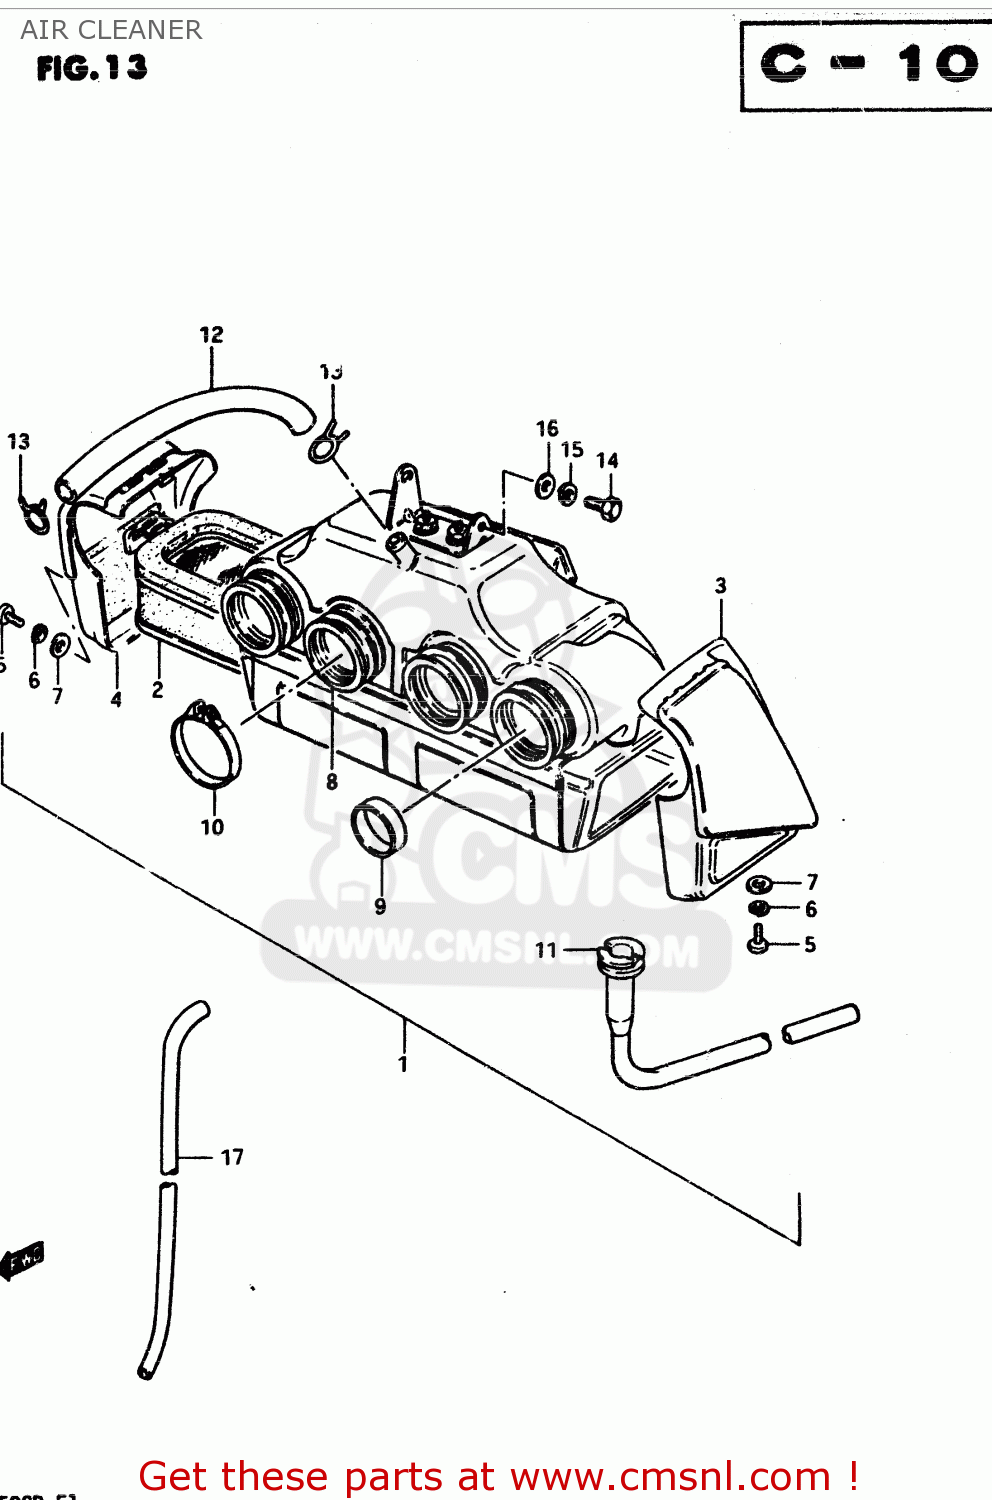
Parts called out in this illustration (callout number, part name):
1	CLEANER ASSEMBLY,AIR
2	FILTER ASSY
3	CAP,AIR CLEANER
4	CAP,AIR CLEANER
5	SCREW
6	LOCK WASHER
7	WASHER
8	TUBE,OUTLET
9	RING
10	CLAMP
11	DRAIN TUBE
12	TUBE,BREATHER
13	CLIP
14	BOLT
15	LOCK WASHER
16	WASHER 6MM
17	HOSE
